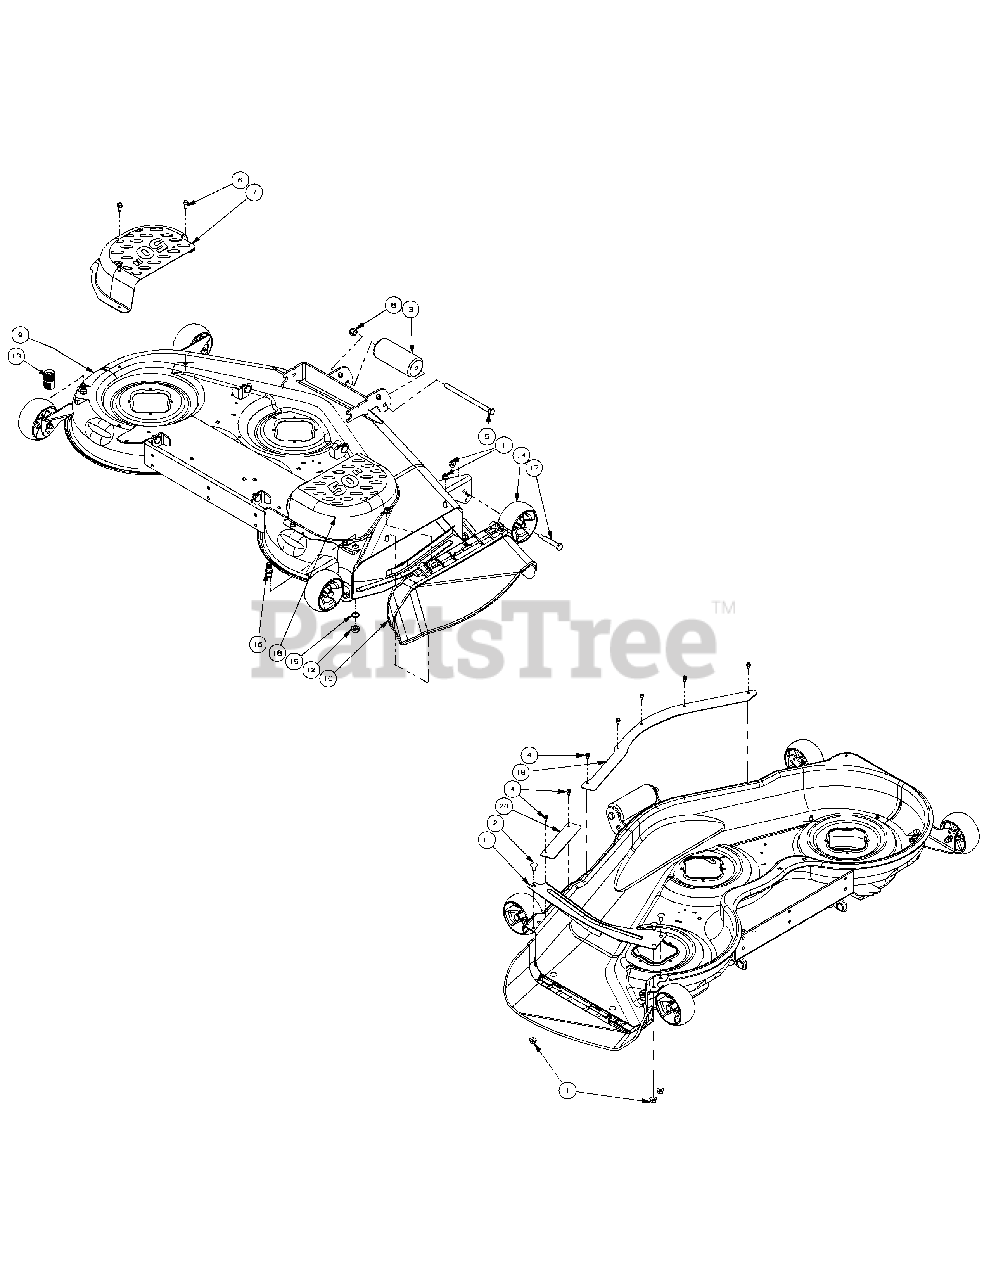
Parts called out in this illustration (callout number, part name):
1	Hex Nut, 3/8-16, Flange Lock
2	Carriage Bolt, 3/8-16 x .75
3	Front Roller
4	Screw, 1/4-20 x 1/2
5	Hex Cap Screw, 1/2-20 x 7.50
6	Self Tapping Screw 5/16-18 x .750
8	Nut, 1/2-20, Lock
10	Chute Assembly
12	Hex Nut, M16-1.5
13	Water Nozzle Adaptor
14	Deck Wheel, 5.00 Dia.
15	Lock Washer, 17 x 23.8 x 1.95
16	Deck Water Nozzle
17	Shoulder Screw .498 x 1.53
